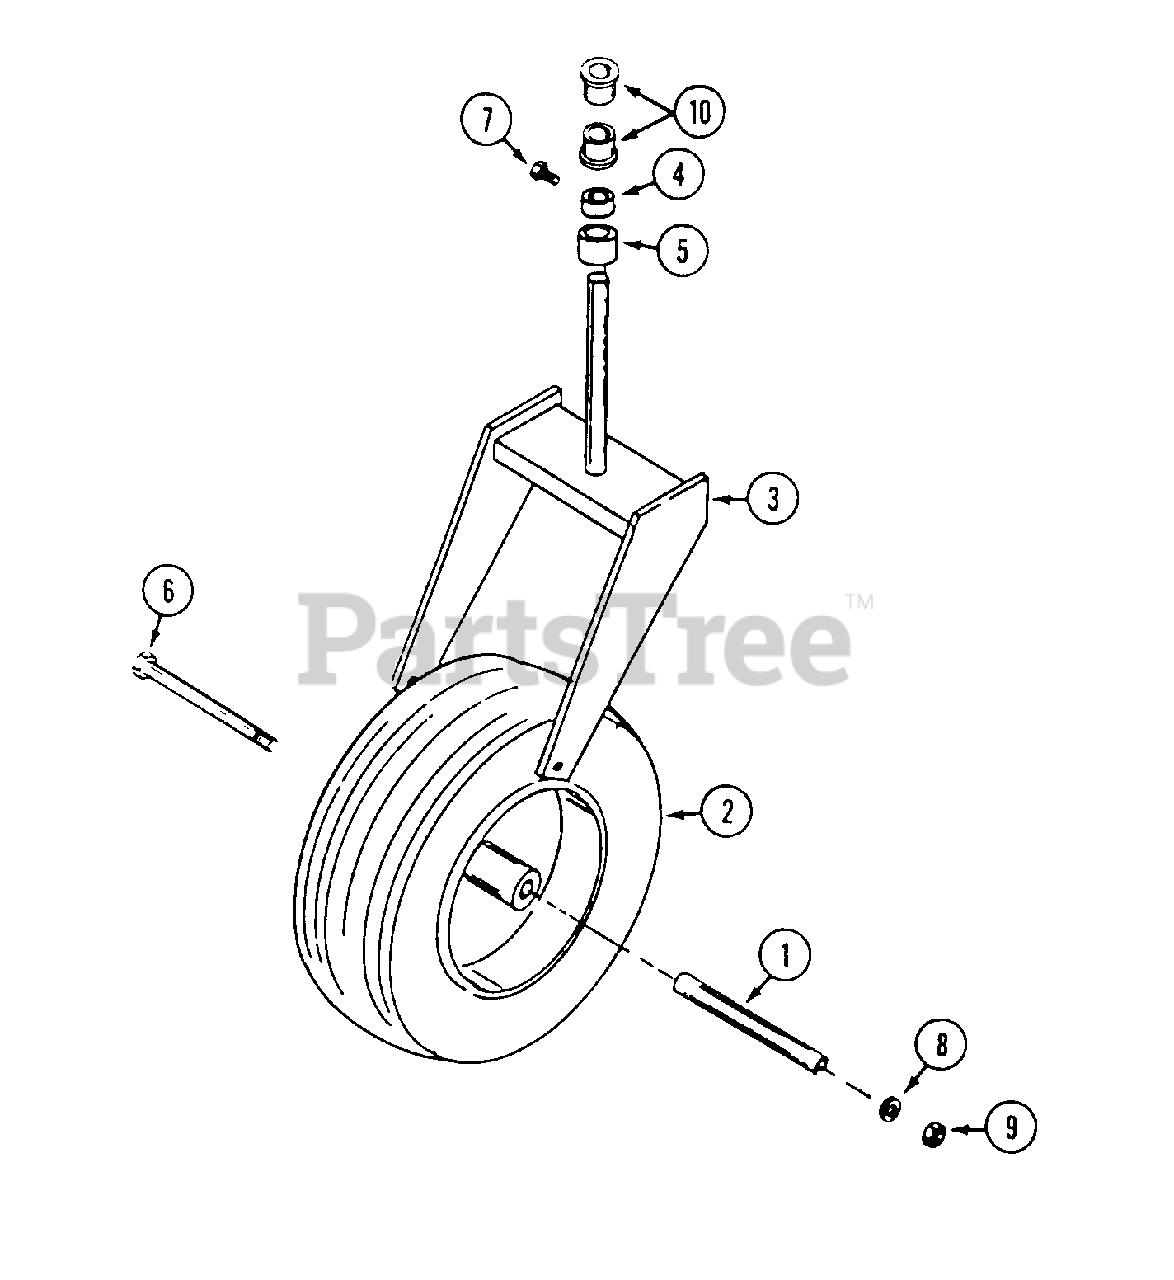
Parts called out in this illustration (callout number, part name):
2	WHEEL ASSEMBLY - tail
3	FORK - tail wheel
4	COLLAR - set 1"
5	SPACER - tail wheel fork
6	BOLT - 1/2" - 13 x 9-1/2"
7	SCREW -set 5/16" - 18 x 1/2" square head
8	LOCKWASHER - 1/2"
9	NUT - 1/2" - 13
10	BEARING - ball 1"
